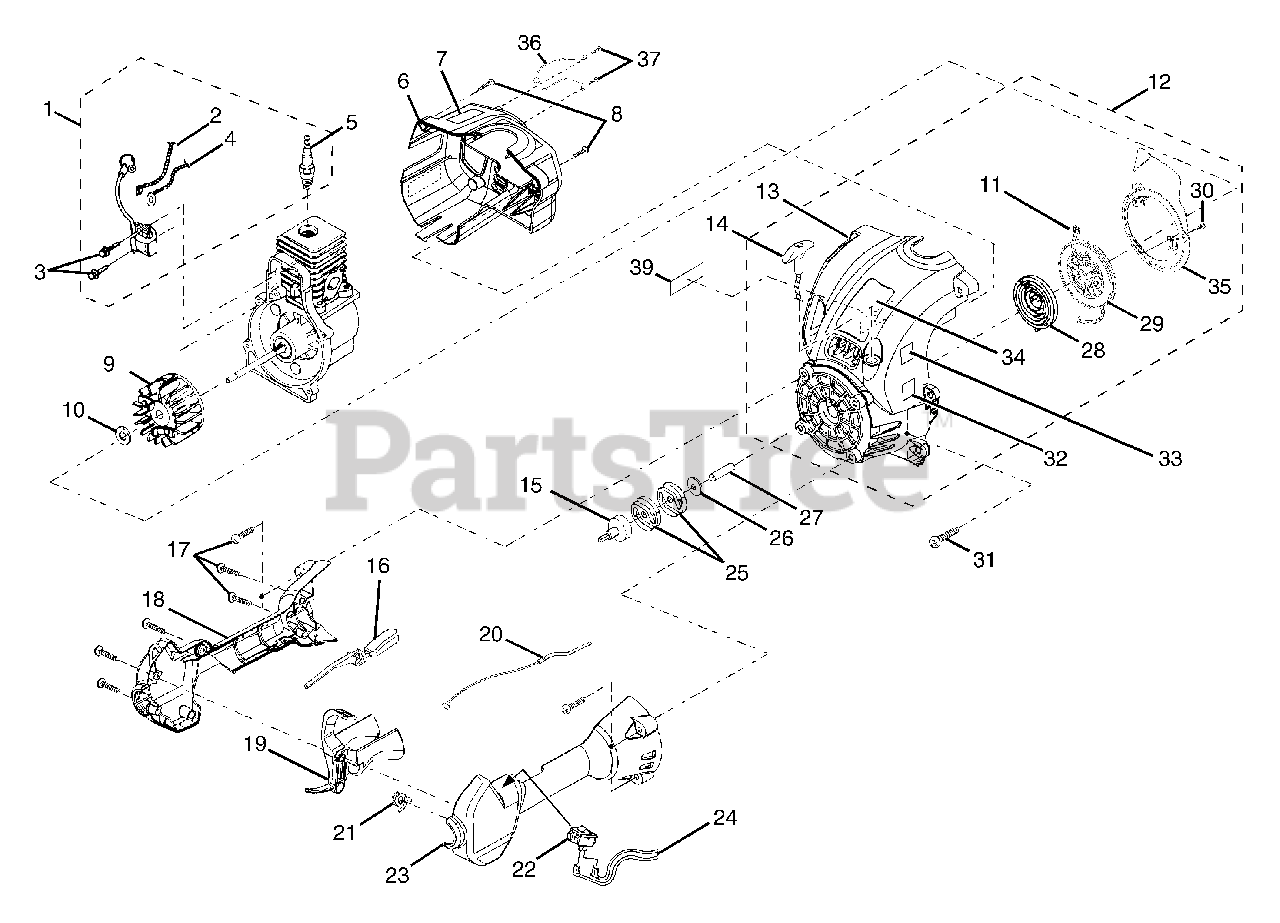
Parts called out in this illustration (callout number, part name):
1	IGNITION KIT
2	ELECTRICAL LEAD
4	ELECTRICAL LEAD
5	SPARK PLUG
6	REAR COVER
7	LOGO PLATE
8	SCREW (10 - 14 x 7/8)
9	ROTOR AND PAWL ASSEMBLY
11	STARTER ROPE 42 in.
12	STARTER ASSEMBLY
13	STARTER HOUSING AND EYELET
14	ERGO GRIP
15	DRUM AND CONNECTOR
16	INTERLOCK TRIGGER
18	CONTROL HANDLE/ RH
20	THROTTLE CABLE
22	SWITCH
23	CONTROL HANDLE/ LH
24	ELECTRICAL LEADS
25	CLUTCH DISK (ST185 & ST385)
26	WASHER
28	SPRING & CONTAINER
29	STARTER PULLEY
32	DECAL, 110 POWER SOUND
33	DECAL, ZIP START
34	DECAL, MODEL
35	AIR BAFFLE PLATE
36	MUFFLER GUARD
39	DECAL, FUEL RATIO MIXTURE
